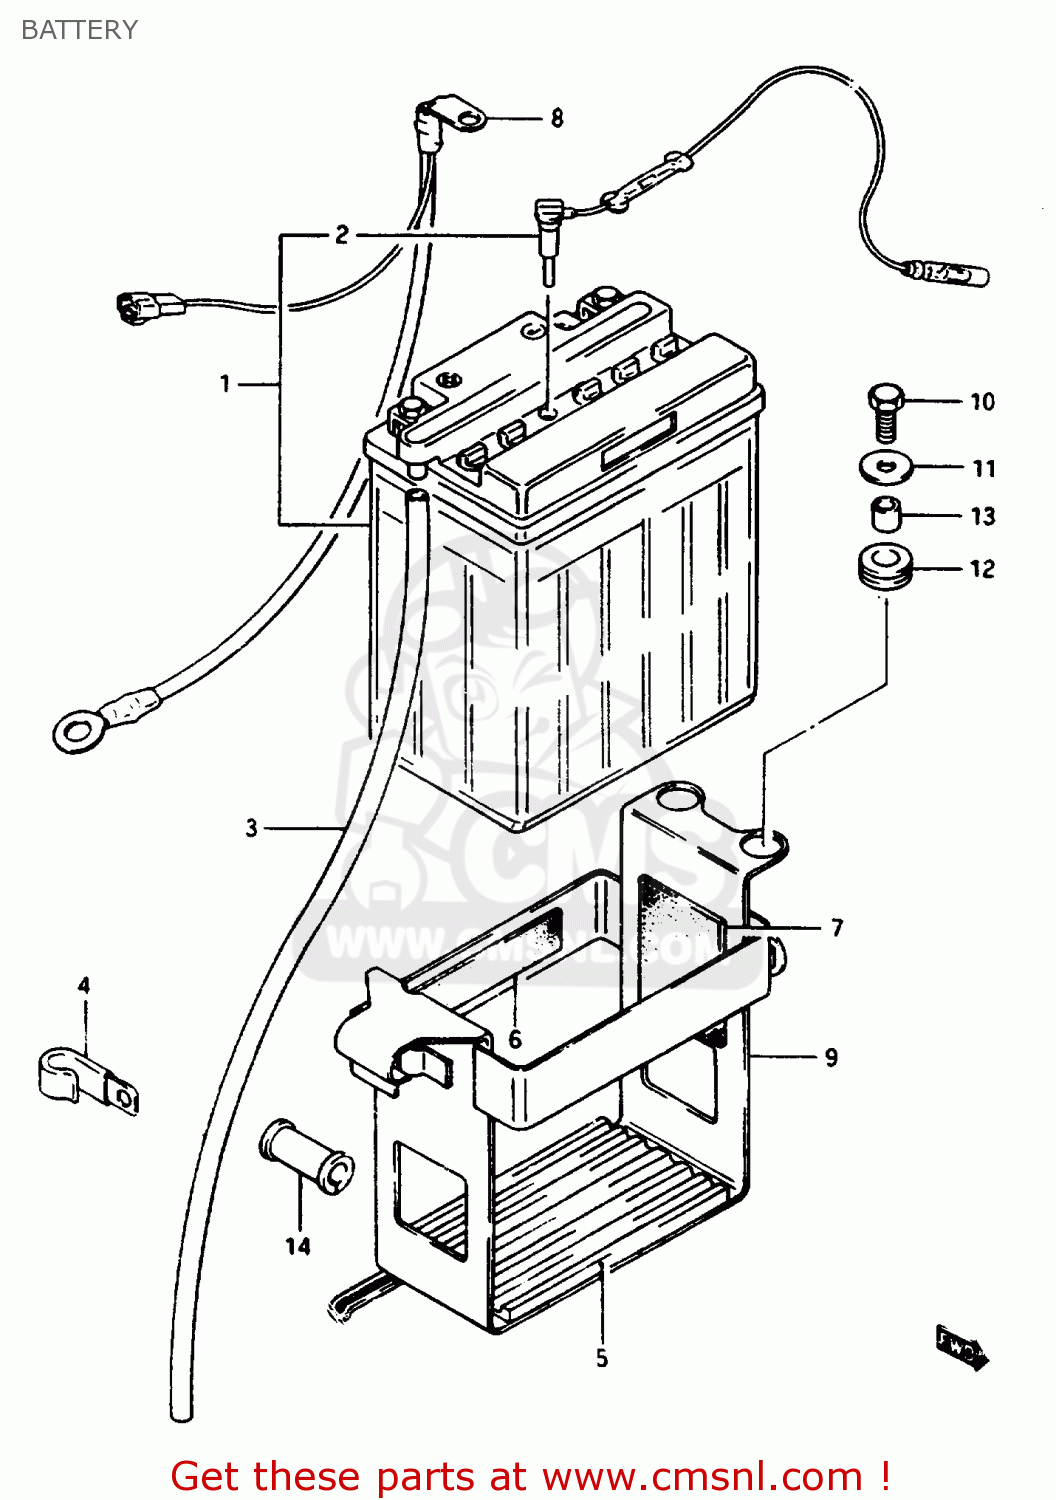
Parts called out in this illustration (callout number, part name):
1	BATTERY ASSY(12V14.7AH)
2	SENSOR,BATTERY LEVEL
3	HOSE,BATTERY EXHAUST
4	CLAMP
5	PROTECTOR,BATTERY
6	PROTECTOR(170X95X3.0)
7	PROTECTOR,BATTERY
8	WIRE,BATTERY MINUS LEAD
9	HOLDER,BATTERY
10	BOLT
11	WASHER
12	CUSHION
13	SPACER(6.1X9X7.5)
14	CUSHION
